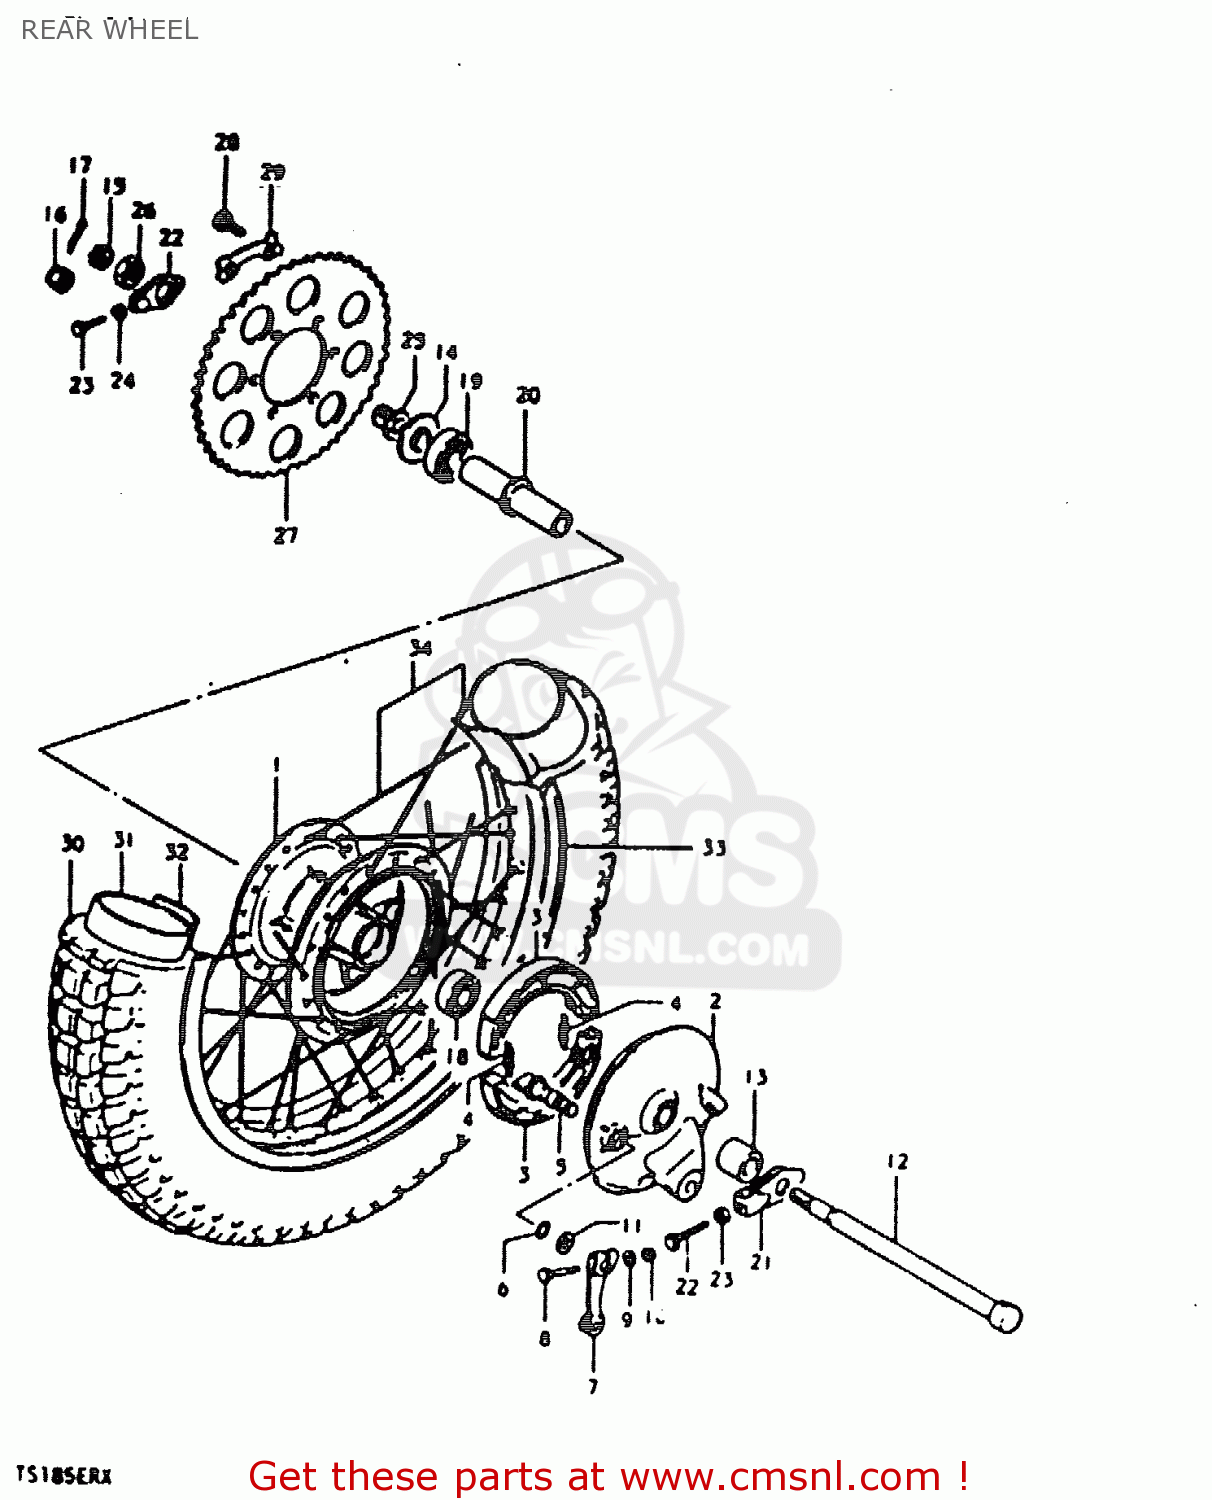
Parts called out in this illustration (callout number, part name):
1	HUB,REAR WHEEL
2	PANEL,RR BRAKE ANCHOR
3	SHOE,BRAKE
4	SPRING(L:34)
5	CAM,FRONT BRAKE
6	O-RING (D:2.4 ID:13.8)
7	LEVER,RR BRAKE CAM
8	BOLT 6X40
9	WASHER
10	NUT
11	WASHER (14.5X22X1.6)
12	AXLE,REAR
13	SPACER(15.2X22X26)
14	SPACER,RR AXLE,L
15	NUT 12MM
17	COTTER PIN
18	BEARING
19	BEARING
20	SPACER,RR WHEEL HUB BEARING
21	ADJUSTER,CHAIN
22	ADJUSTER,CHAIN,L
23	BOLT(8X40)
24	NUT
25	SPACER,CHAIN ADJUSTER,L
26	NUT
27	SPROCKET,RR
28	BOLT(8X30)
29	WASHER
30	TIRE 4.10-18 105-458MM
31	TUBE ASSEMBLY,WHEEL,INNER
32	PROTECTOR,INNER TUBE
33	RIM,WHEEL(1.85X18)
34	SPOKE SET
